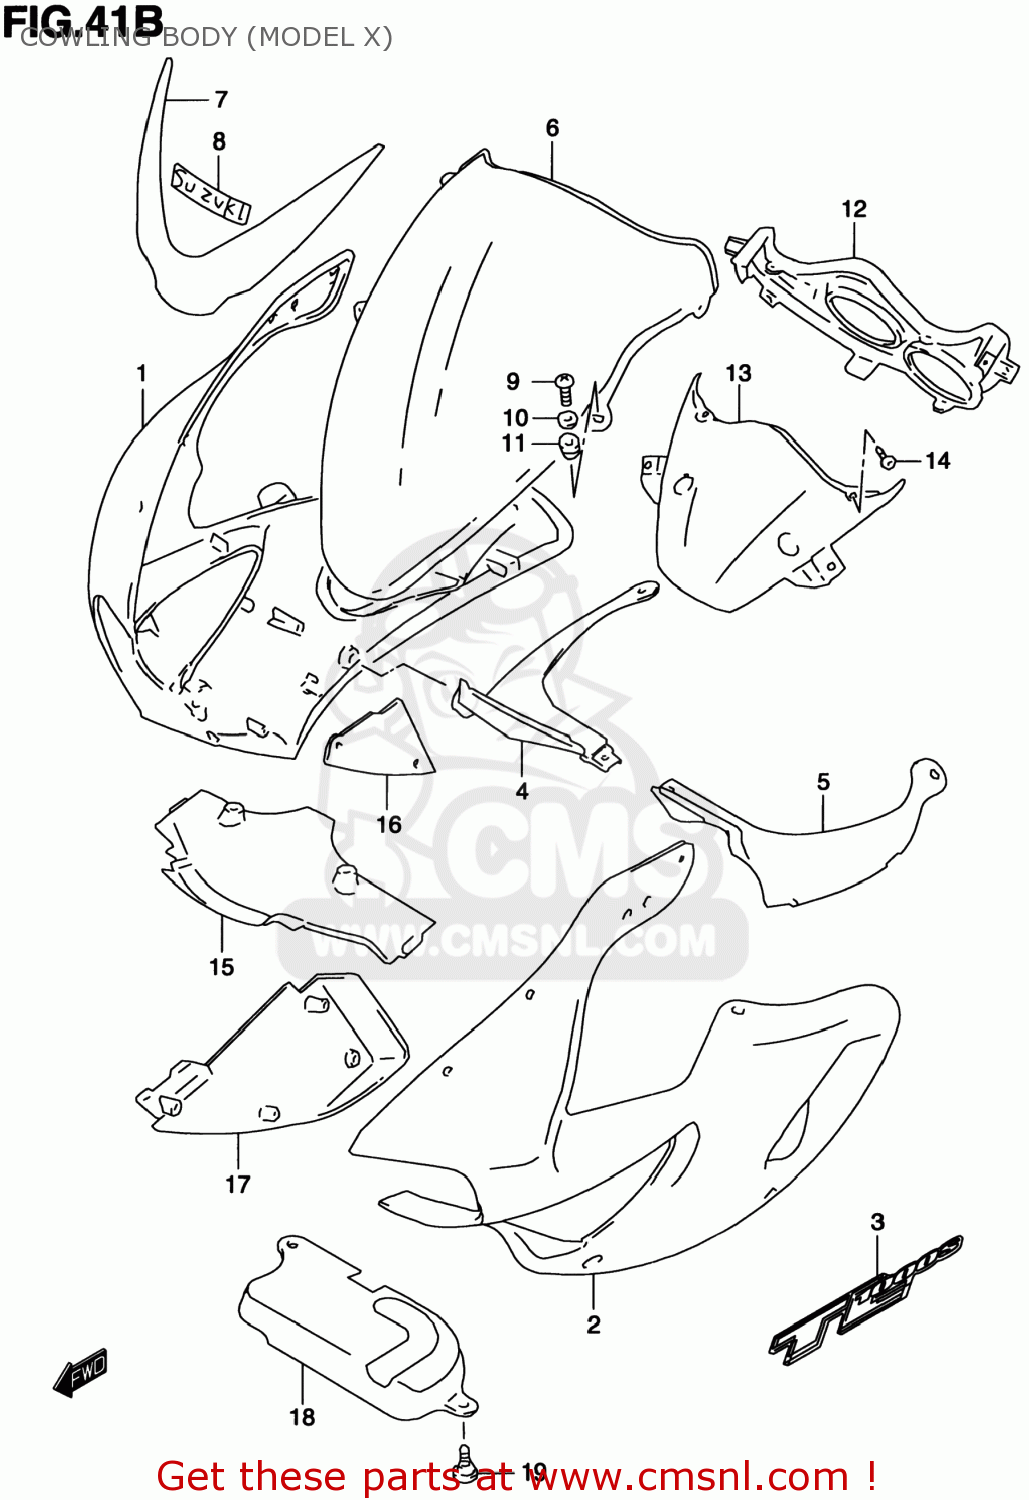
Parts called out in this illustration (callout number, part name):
1	COWLING,SIDE,R(BLUE)
2	COWLING,SIDE,L(BLUE)
3	EMBLEM,COWLING SIDE
4	PANEL,SIDE,R
5	PANEL,SIDE,L
6	WINDSCREEN(SILVER)
7	TAPE,WINDSCREEN
8	EMBLEM(SILVER)
9	SCREW(5X14)
10	WASHER
11	NUT
12	PANEL,METER
13	PANEL,FR
14	CLIP(BLACK)
15	COWLING COMP,CENTER,LOWER
16	COWLING,INNER,R
17	COWLING,INNER,L
18	COVER,COWLING FR LWR
19	BOLT
